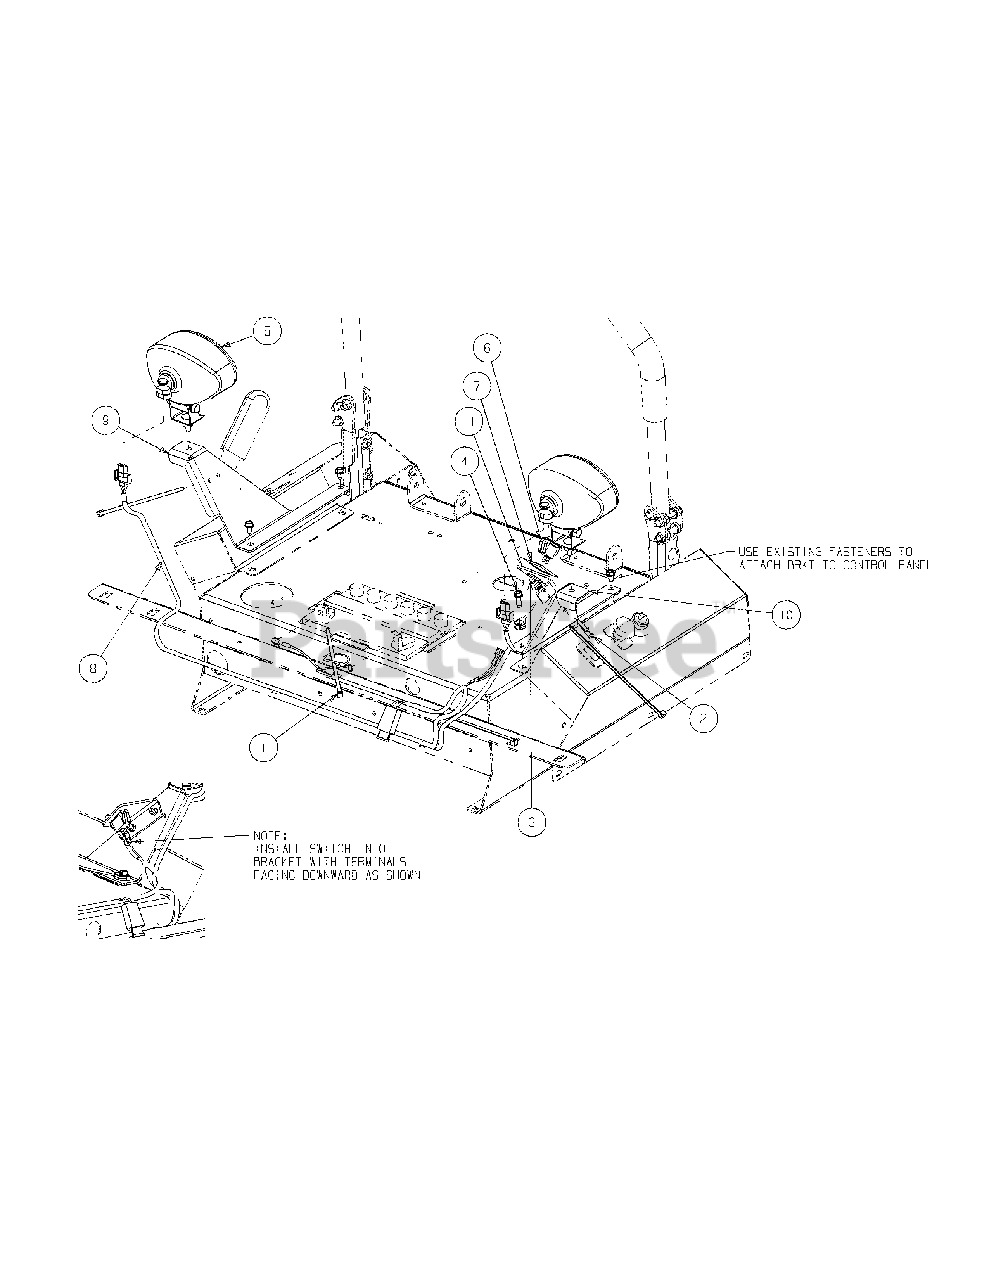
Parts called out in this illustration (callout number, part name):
1	Cable Tie
2	Phillips Head Machine Screw, 10-32 x 5/8
3	Nut, #10-32, Nylon Lock
4	Self Tapping Screw, 1/4-20 x .75
5	Oval Work Lamp
6	Switch
7	Label, Headlamp, On/Off
8	Harness Assembly
